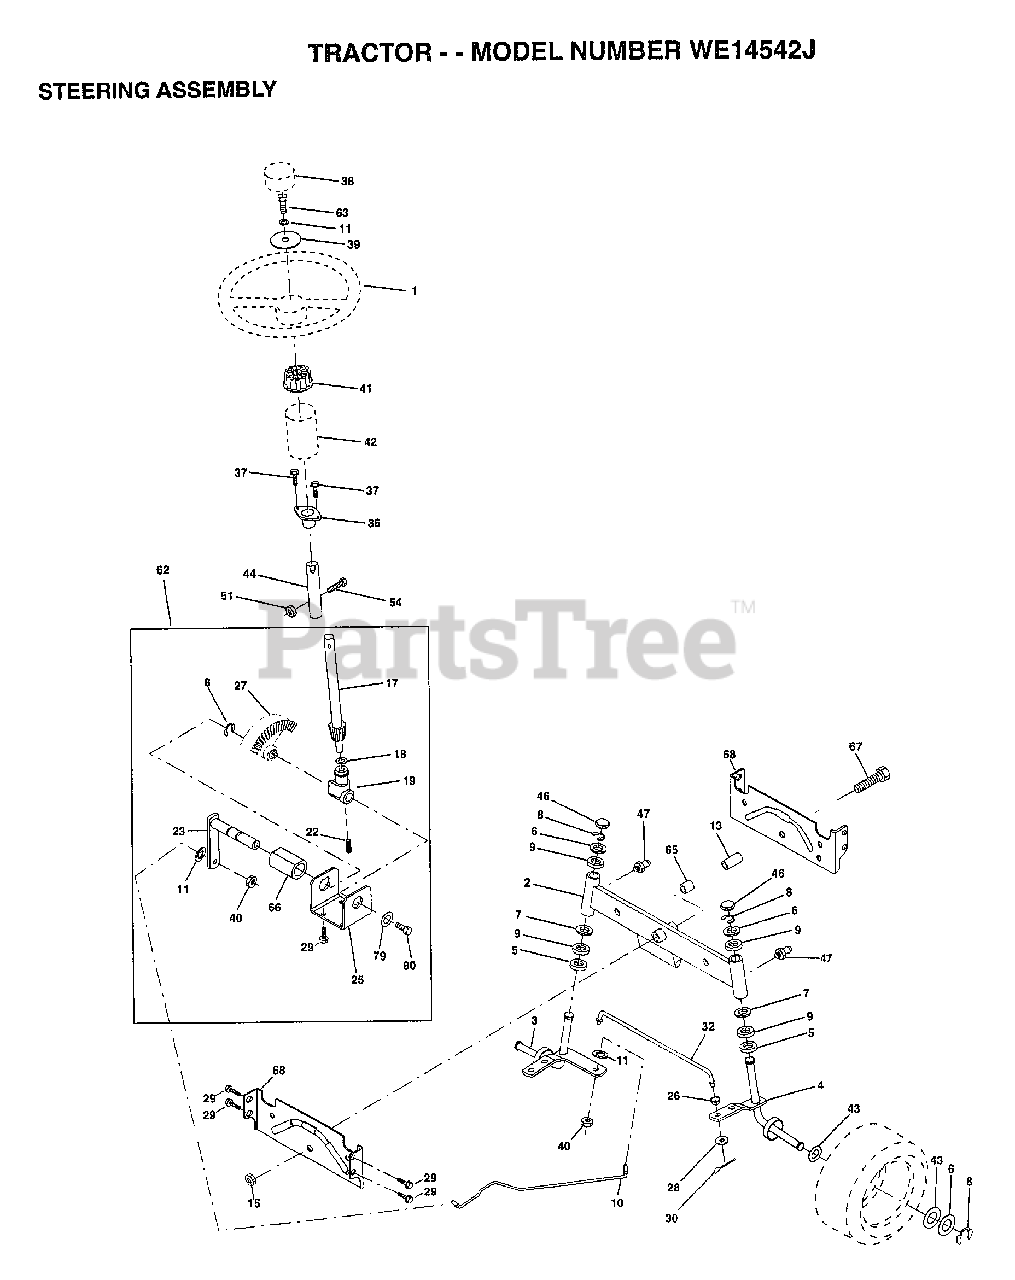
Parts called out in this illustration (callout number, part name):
1	WHEEL STR AYP BLK
2	AXLE ASM
3	SPINDLE.ASM.LH
4	"SPINDLE ASM,RH"
5	WASHER .T
6	WASHER
7	WASHER
8	RING
9	COL. SRTG. BEAR.
10	DRAGLINK-STAMPED
11	LOCKWASHER
13	BEARING AXLE
15	"NUT-LOC,FLANGE LT"
17	SHAFT ASM STEERIN
18	THRUST WASHER
19	SUPPORT.SHAFT.STEER
22	SCREW.HX.WSH.HD
23	SHAFT.ASM.PITMAN
25	BRKT-STEERING
26	BUSHING.DRAGLINK
27	GEAR SECTOR
28	WASHER
29	SCREW
30	COTTER PIN
32	TIE ROD
36	BUSHING.STEERING
37	"SCREW-TT,10-32 FL"
38	CAP STEER AYP
39	WASHER T
40	GRIPCO NUT
41	ADAPTER LT
42	BOOT.STEER.PL
43	WASHER
44	EXT SHAFT STEERIN
46	CAP
47	ZERK M
51	NUT
54	BOLT
62	KIT.STEER.ASM
63	BOLT
65	SPACER AXLE
66	"BEARING-ARM,PITMA"
67	BOLT
68	BRACE AXLE
79	WASHER
80	BOLT.HX.NYLON3/8-16X3/
